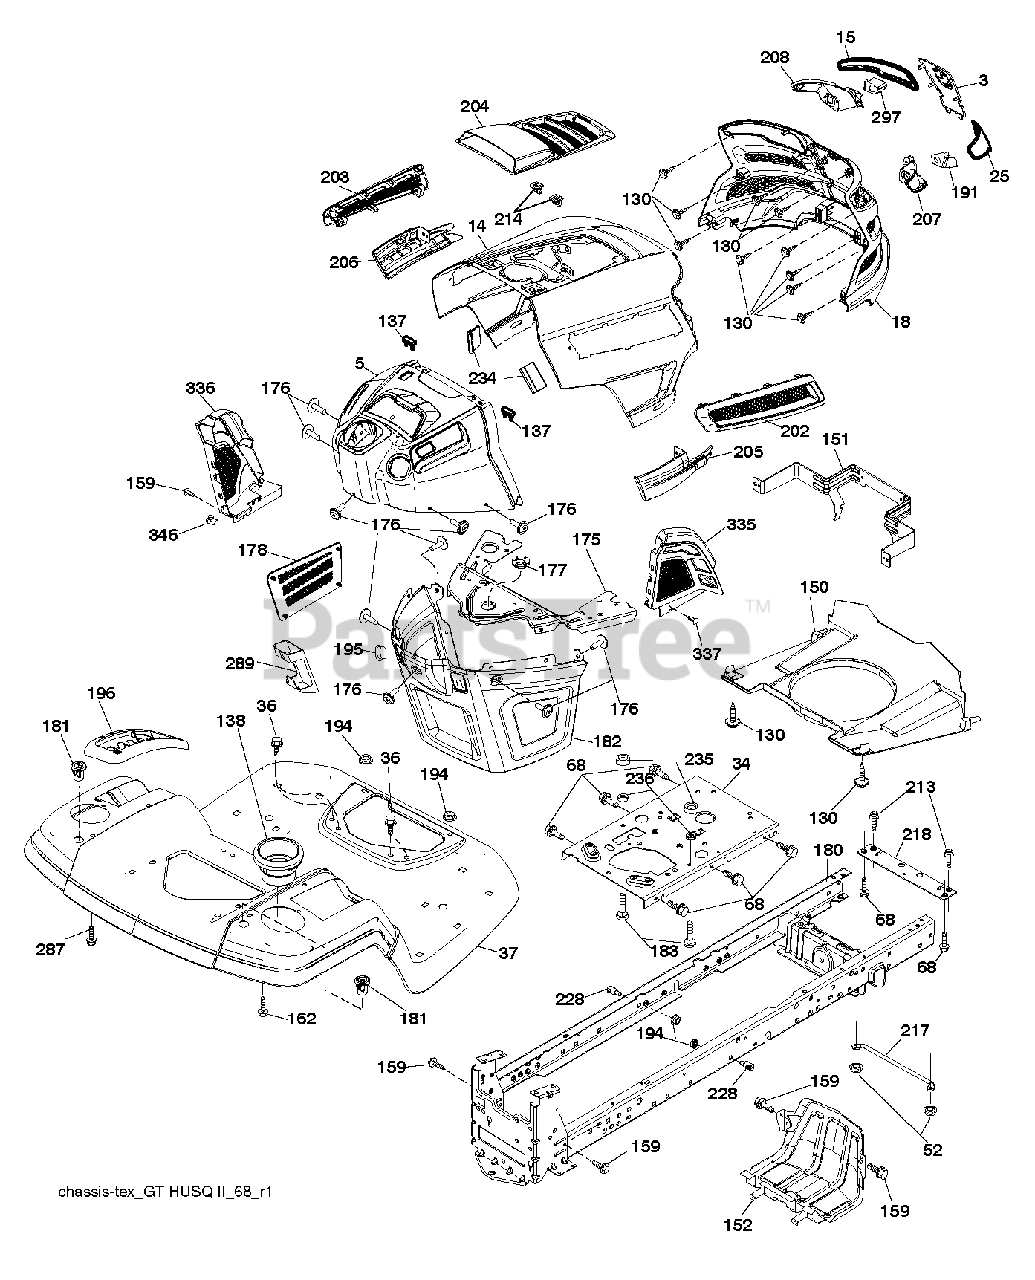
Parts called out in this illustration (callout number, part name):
3	APPLIQUE.SUBASM.GT.HUSQ.II
5	RP.DASH.UPP.GT2.SM.MC.CHOKE
14	HOOD.ASM.HUSQVARNA.GT.TEX.422
15	LENS.HEADLIGHT.LH.GTII.2011
18	GRILLE.SUBASM.GT.HUSQ.II
25	LENS.HEADLIGHT.RH.GTII.2011
34	PLATE.ENGINE.WELDED.CHASSIS
36	SCREW 5/16"
37	RP FENDER.TLT.FS.W/CPH.422
52	LOCKNUT
68	SCREW LT
130	SCREW.#10 X 0.750.BOS
137	BUMPER DASH
138	HOLDER.CUP.LT.GREY
150	AIR DUCT.GTV2(1.66"RING HEIGHT
151	BRACKET.PIVOT.HOOD.GT.HUSQ.II
152	SHIELD.BROWNING.PNT.GT.V2
159	SCREW, 3/8-16X3/4
162	SCREW.HI-LO.CONSOLE
175	PLATE.CROSSMEMBER.HUSQ
176	SCREW.#10-24X5/8.RN.QU
177	BUSHING, STEERING
178	CARGO.ASM.NET.TXGT.W/C
180	CHASSIS
181	BUSHING.MNT.FEND.CRGO.TEX.49
182	DASH.LOWER.COMMON.12V.ADAPTOR
183	BOLT.5/16-18X1-1/4 FULL THD
191	INSERT.REFLECTIVE.RH.HUSQ.GTII
194	NUT LOCK HEX FLANGE 5/16-18
195	DECKLFT.CONSOL FULL ASSM GREY
196	CONSOLE.ASM.DCKLFT.RBT.TLT.498
202	VENT.SIDE.RH.GT.HUSQ.II.
203	VENT.SIDE.LH.GT.HUSQ.II.498
204	VENT.TOP.HUSQ.GT2
205	SIDE.TRIM.RH.GT.HUSQ.II
206	SIDE.TRIM.LH.GT.HUSQ.II.GRAY
207	BEZEL LIGHT.RH.GT.II.MYLAR
208	BEZEL LIGHT.LH.GT.II.MYLAR
213	BOLT
214	CLIP.RETAINER.TINNER.
217	ROD.PIVOT.HOOD
218	X-PIECE.HOOD.STOP.NON/
228	STUD.FASTNER.W/ANTI-ROTATE
234	BUMPER.HOOD.TEX.HUSQVARNA
235	SPACER FENDER
236	NUT.CENTERLOCK.5/16-
287	SCREW 1/4X20
289	PLUG.N/CRUISE.COMMON.YT/GT.BLK
297	INSERT.REFLECTIVE.LH.HUSQ.GTII
335	COVER.RH.CLOSE.OUT.BLACK
336	COVER-LH.LOWER.DASH.GT2.BLACK
337	CLIP.XMAS.TREE.ITW.2622-00
346	CLIP,INSULATOR
